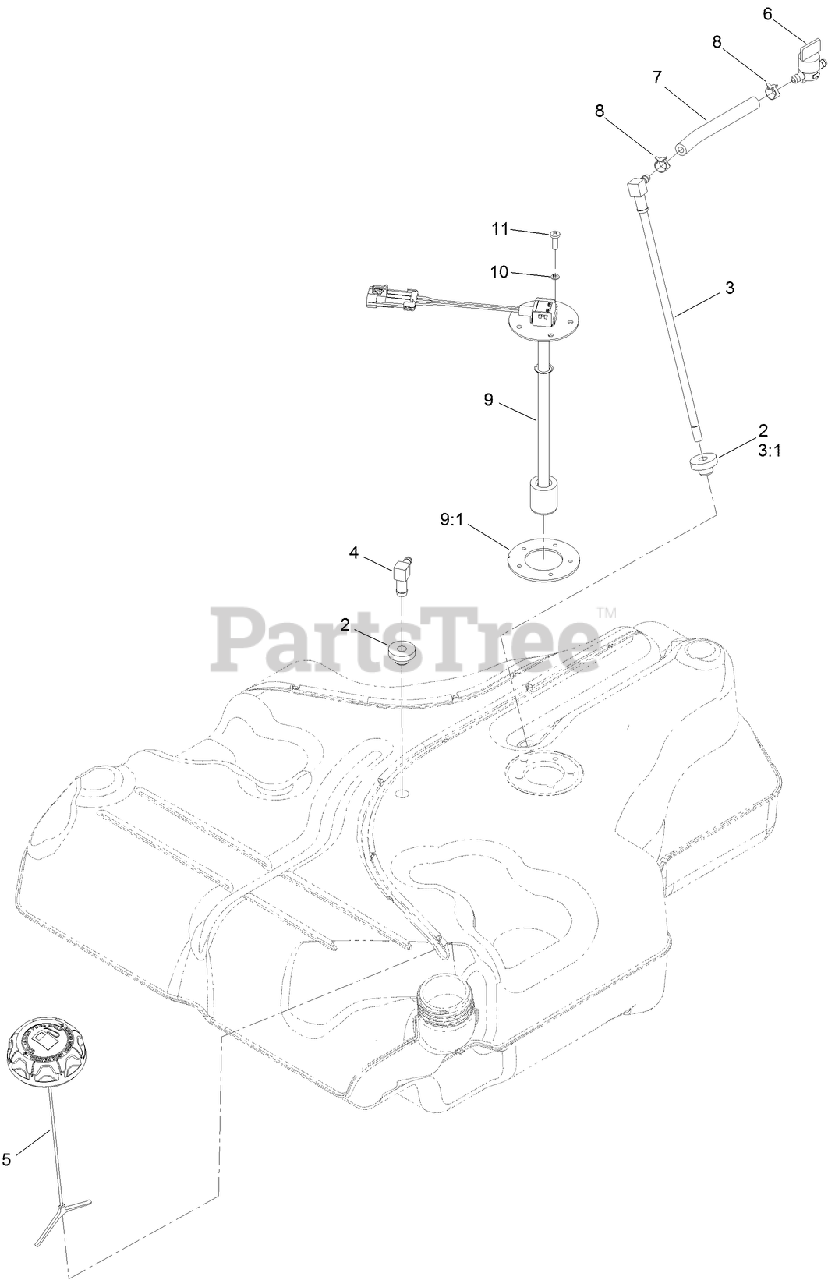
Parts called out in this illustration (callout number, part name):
2	BUSHING
3	FUEL LINE KIT (WITH GROMMET)
3:1	BUSHING
4	FITTING-90 ELBOW
5	CAP-FUEL, RATCHETING
6	VALVE-FUEL
7	HOSE-FUEL
8	CLAMP-HOSE
9	SENDER-LEVEL, FUEL (W/GASKET)
9:1	GASKET-SENDER
10	WASHER-LOCK
11	SCREW-PPH
